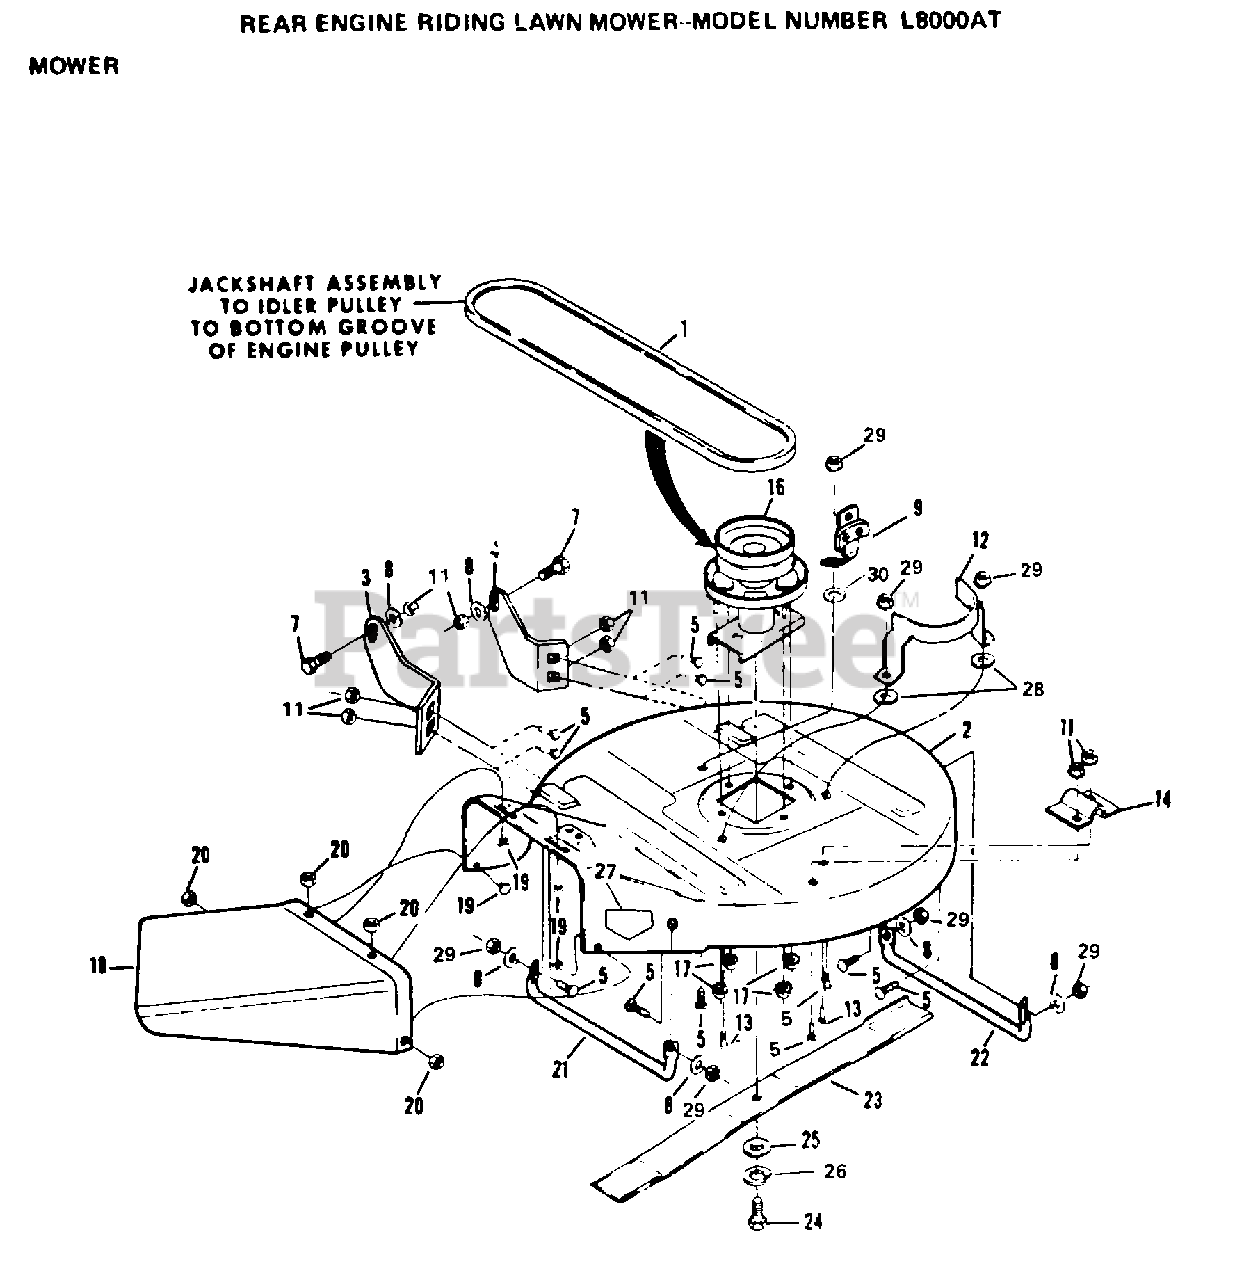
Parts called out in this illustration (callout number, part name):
2	HOUSING W/SILK SCREENING
3	HOUSING LIFTE T
4	HOUSING LIFTE T
5	BOLT
7	SHOULDER BOLT T
8	WASHER M
12	BELT SNUBBER T
14	MOWER SUPPORT T
16	JACKSHAFT ASS T
18	DISCHARGE GUARD
26	LOCKWASHER
